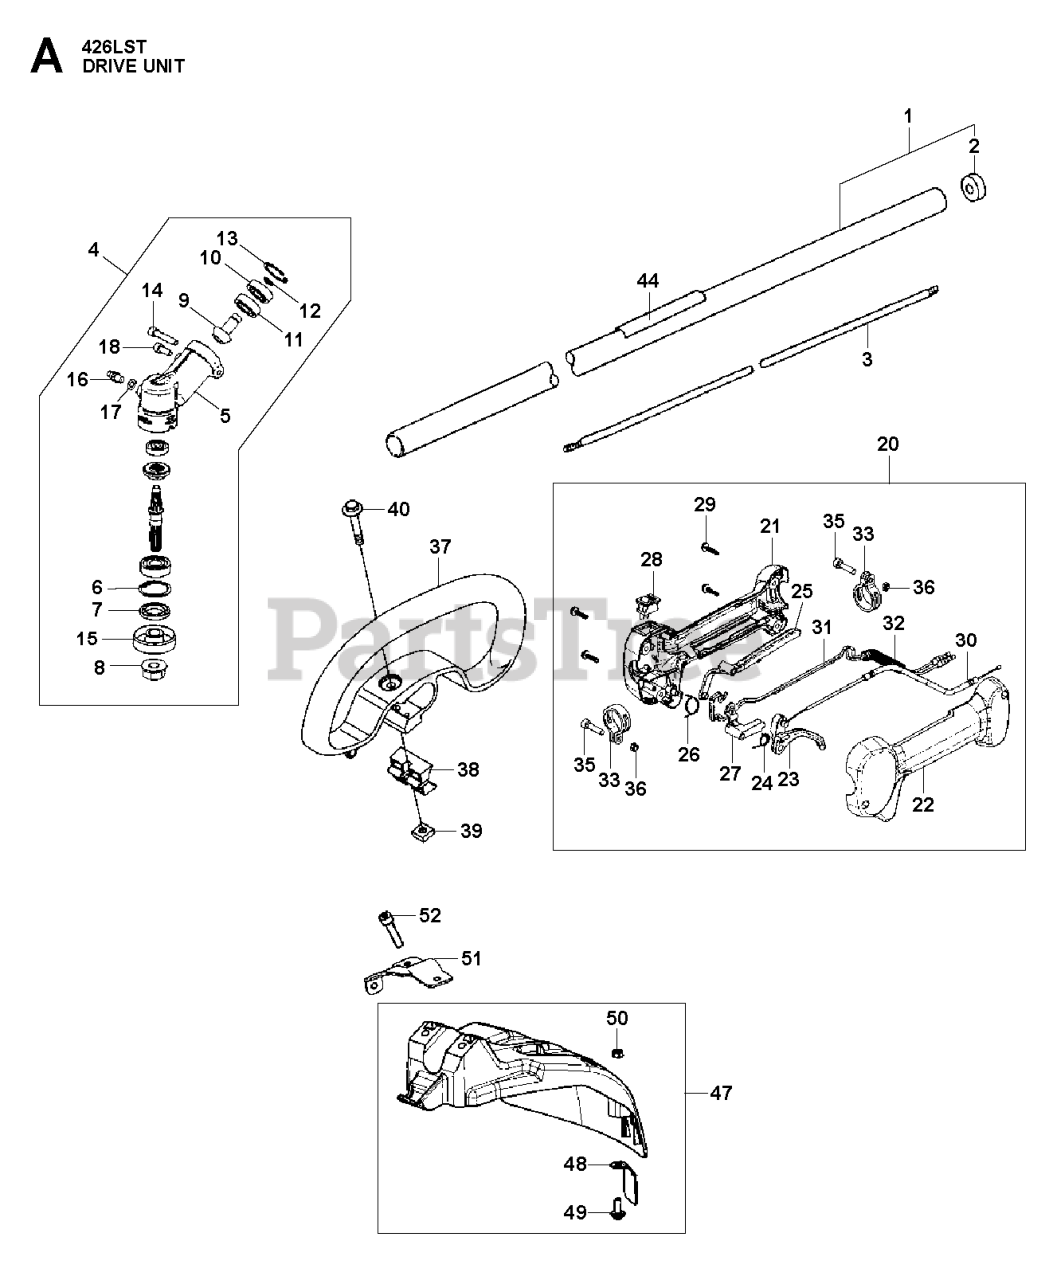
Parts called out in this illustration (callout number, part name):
1	STARTER ASSY
4	STARTER ROPE
5	STARTER HANDLE
7	DRIVER PULLEY
8	SPRING - DRIVER
9	STARTER PULLEY
10	STARTER PULLEY
12	STARTER HOUSING
14	STARTER PAWL BRIDGE
17	STARTER PAWL
18	DECAL DEVICE
18	DECAL, STARTER HOUSING
18	DECAL
22	SCREW IHSCFMO
